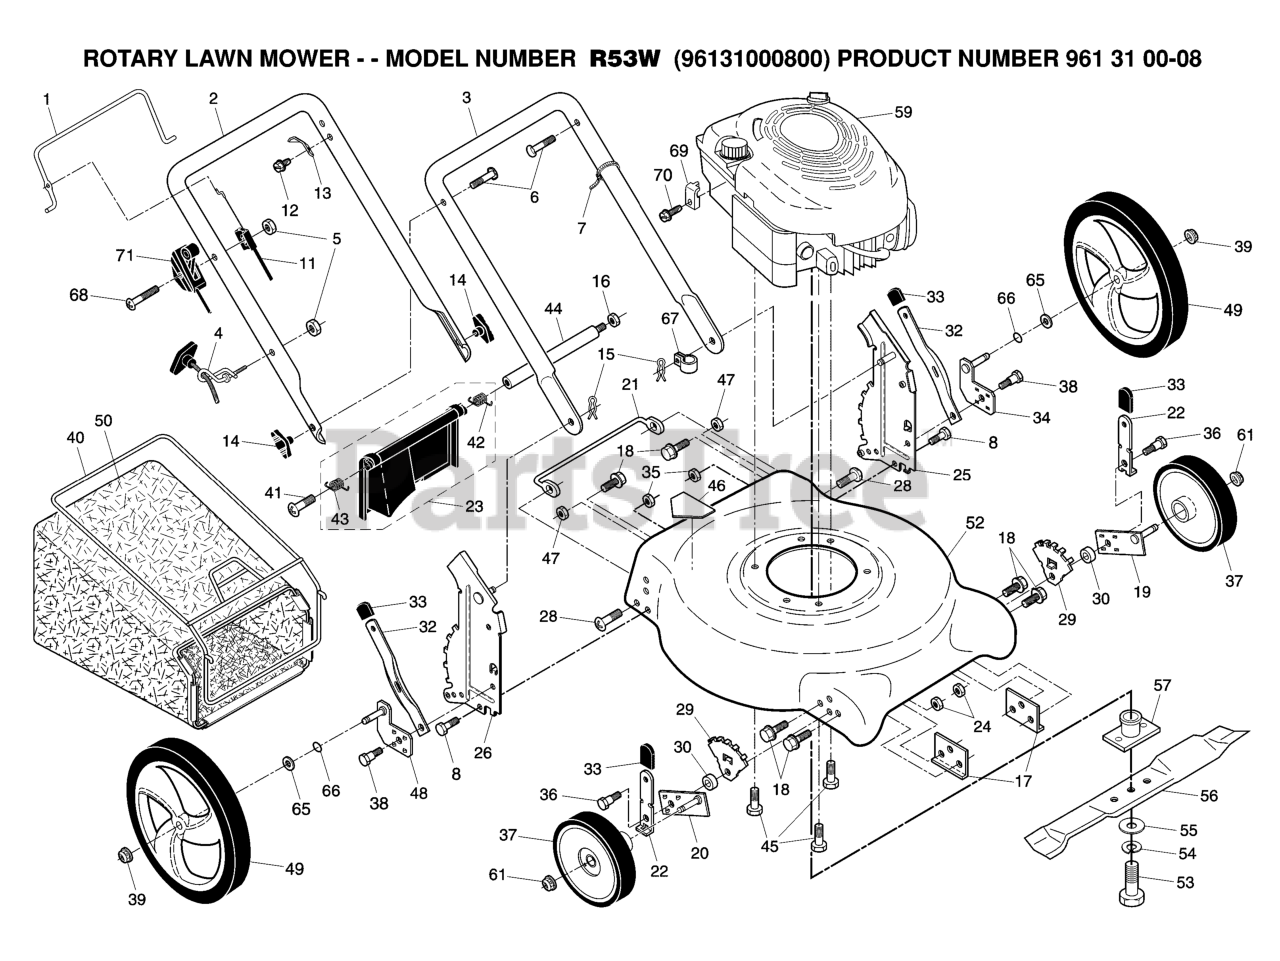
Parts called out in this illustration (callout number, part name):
1	BAIL.MZR.STD.BLACK
2	Upper Handle
3	HANDLE.LOWER.GREY
4	RB GUIDE.ROPE.STD.BLK.ZIN WSL
5	NUT
6	BOLT, HANDLE 5/16-18X1.75
7	TIE GUIDE
8	BOLT.FIN.HEX.5/16-18X3/4
11	ENGINE ZONE CONTROL
13	BRACKET
14	KNOB, DEFLECTOR
15	HAIRPIN COTTER
16	NUT.HEX.FLANGE.1/4
17	SUPPORT BRACKET
18	SCREW 1/4X20
19	AXLE ARM ASSY
20	AXLE ARM ASSY LF
22	REPL BY 532 1683-60
23	KIT.REAR.DOOR.21.DOMED.
24	NUT.CENTERLOCK.5/16-
25	BRACKET.ASM.HAND.HW.21.LT.BLAC
29	WHEEL BRACKET ADJUSTER
30	SPACER.34X1.38X.22
32	SPRING.SEL.EXT.21.DOME
34	ARM.ASM.AXLE.REAR.LT.B
35	LOCKNUT 5/16-18
36	SHOULDER BOLT
37	WHEEL.8X1.75.MAG2.BRK.GRY.TB.1
38	SHOULDER BOLT
39	NUT
40	FRAME.BAG.21.REAR.DOME
41	HINGE SCREW
42	SPRING (LH)
43	SPRING (RH)
44	ROD.STIFFENER
45	BOLT 3/8-16X1-1/8
46	DECAL.INTERNATIONL.CUTFINGER
47	NUT.71038.31-18.HEX.NYLOCK
48	ARM.ASM.AXLE.REAR.RT.BZP.RECS
49	WHEEL.12X1.75.
53	SCREW, HEX HD 3/8-24 X 1-3/8
54	LOCKWASHER
55	WASHER,HARDEN
56	BLADE.21.PUSH
57	ADAPTER.BLADE
61	HEX FLANGE LOCKNT
65	WASHER.FLAT.1/2
66	O-RING..070X.487.NEOPRENE
67	CLIP.CABLE.BLK
69	CABLE CLAMP(ENGINE)
70	SCREW.HEX.HEAD.WASHER.10-16
71	THROTTLE CONTROL
